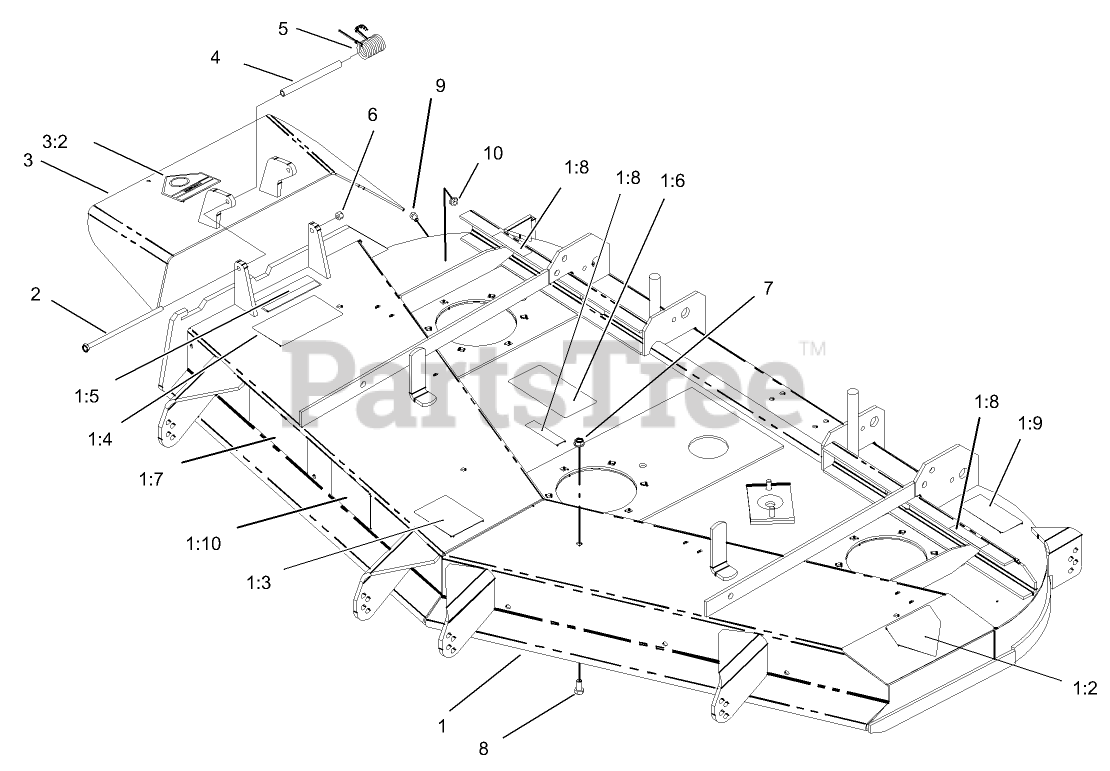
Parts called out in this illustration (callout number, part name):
1	Deck ASM
1:2	DECAL-DANGER
1:3	DECAL-WHEEL, GAGE
1:4	DECAL-DANGER, THROWN OBJECT
1:5	DECAL-WARNING
1:6	DECAL-ROUTING, BELT
1:7	DECAL-SFS
1:8	DECAL-COVER, MISSING
1:9	DECAL-TORQUE, BLADE BOLT
1:10	DECAL-DECK
2	SCREW-HH
3	Deflector ASM
3:2	DECAL-DANGER
4	SPACER
5	SPRING-TORSION
6	NUT-LOCK, NI
7	NUT-HHF, WHIZ
8	SCREW-HH
9	SCREW-HH
10	NUT-HF
